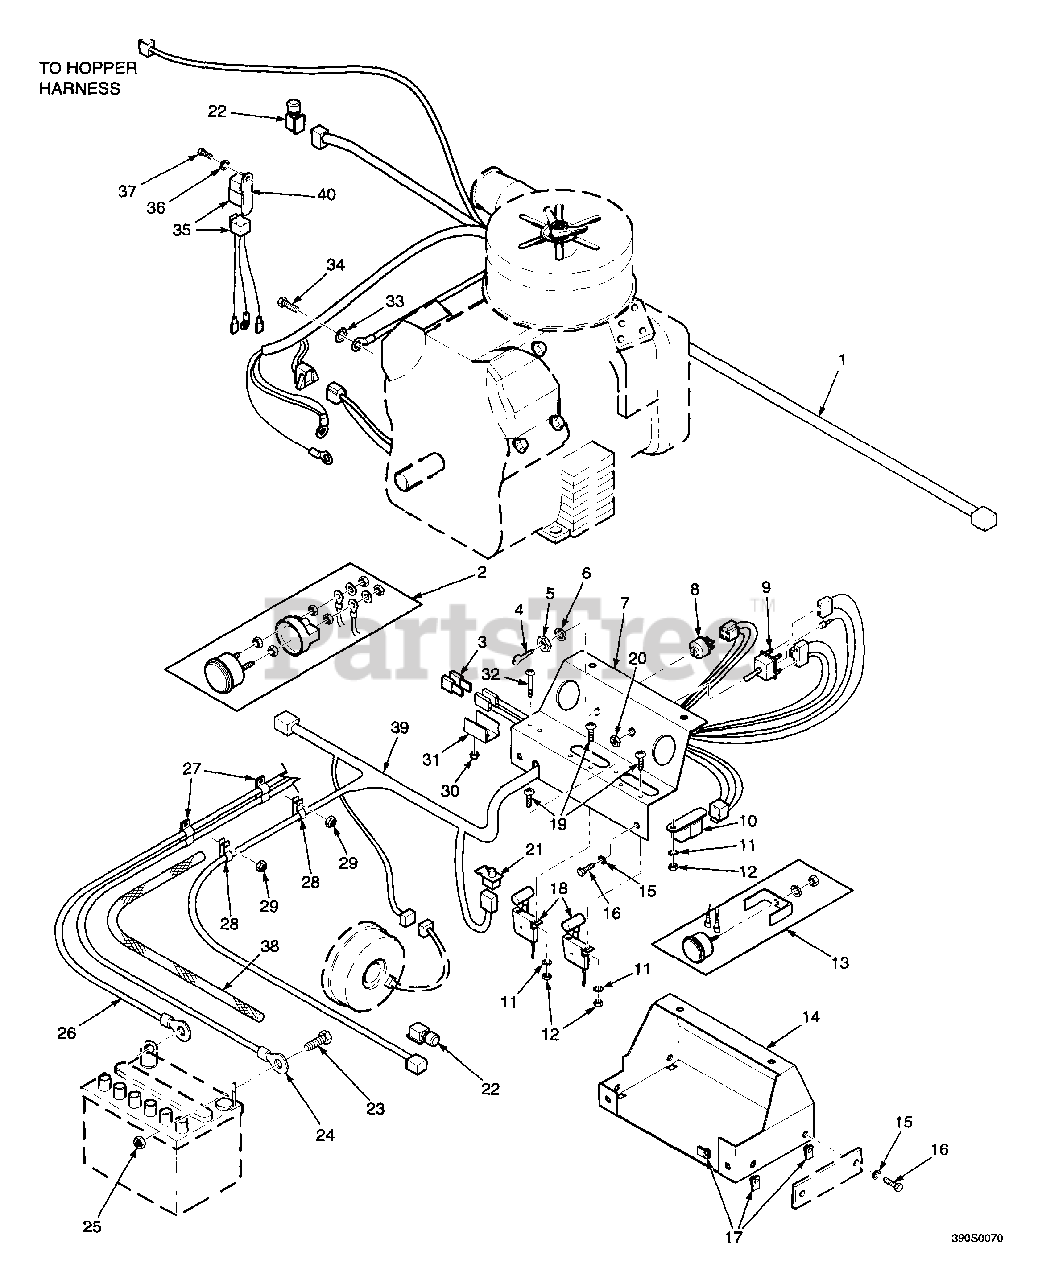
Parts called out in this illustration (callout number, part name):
1	Harness, Engine
2	Hourmeter
3	Fuse, 20 Amp
4	Key & Ring Assembly
5	Nut, Hex, 5/8-32
6	Lockwasher, 5/8 Internal
7	Instrument Panel, Top With Decal
8	Keyswitch
9	Switch, Mower Engagement Electric Clutch
10	Relay
11	Lockwasher, #10 External Tooth
12	Hex Locknut, Elastic Stop, #10-32
13	Ammeter
14	Base, Instrument Panel
15	Lockwasher, 1/4"
16	Bolt, Hex Head, 1/4-20 x 3/4"
18	Throttle and Choke Controls
19	Screw, Washer Round Head, #10-32 x 1/2"
20	Nut, Hex, 1/2-27
21	Switch, Interlock - Seat
22	Switch, Interlock - (Neutral and Hopper)
23	Bolt, Hex Head, 1/4-20 x 1/2"
24	Cable, Battery - Red
25	Nut, Hex, 1/4-20
26	Cable, Battery - Black
27	Clamp, Double Cable
28	Clamp, Cable
29	Hex Locknut, Elastic Stop, 5/16-18
30	Hex Locknut, Elastic Stop, #10-32
31	Bracket, Fuse Holder
32	Screw, Round Head, #10-32 x 1-1/2"
33	Lockwasher, External Tooth, 5/16
34	Bolt, Hex Head, M8-1.25 x 20
35	Relay and Harness
36	Lockwasher, 1/4
37	Bolt, Hex Head, M6-1.125 x 10
38	Nylon Sleeve, 24"
39	Wire Harness, STR
40	Relay
